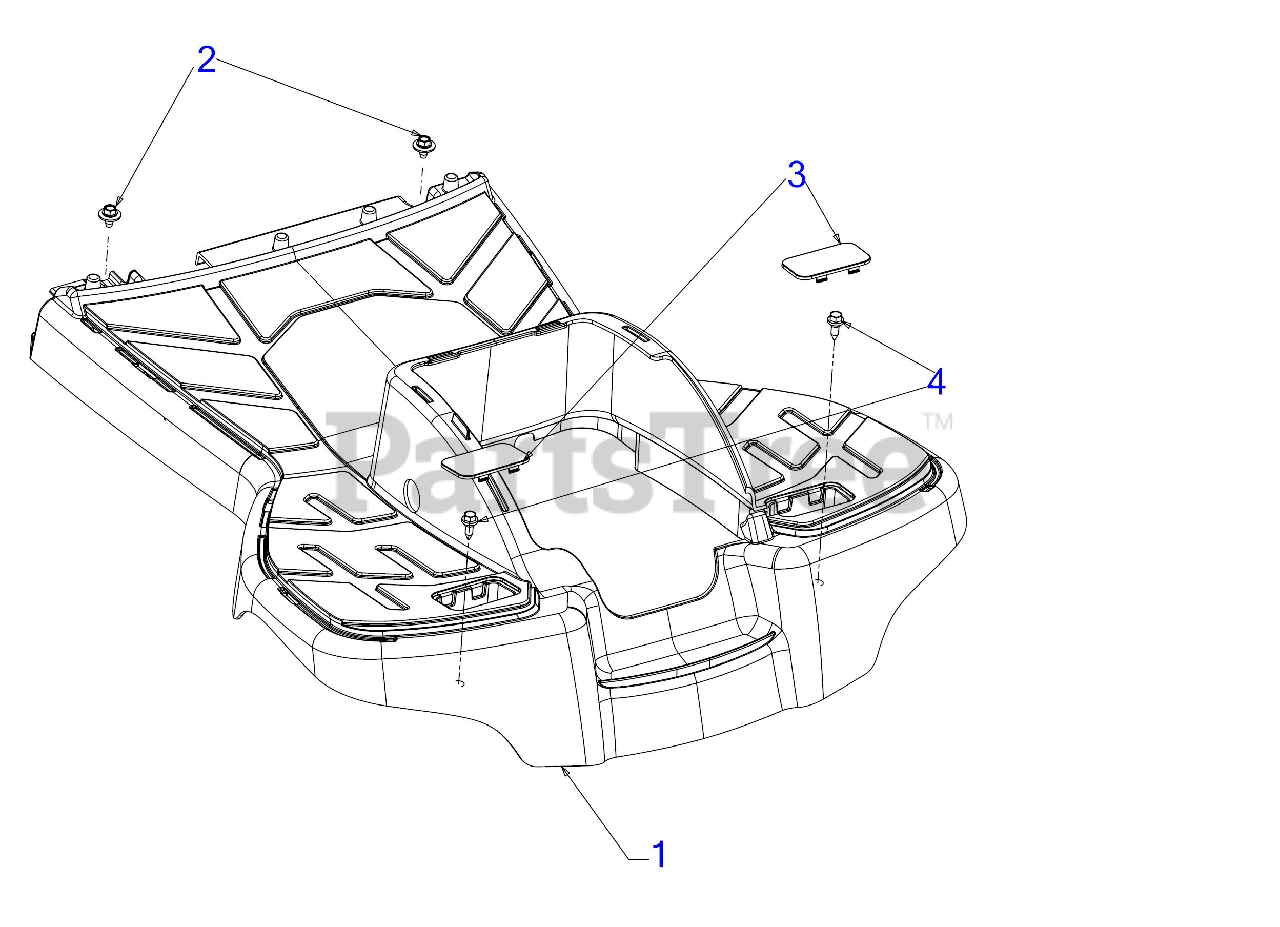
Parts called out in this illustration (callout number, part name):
1	RUNNINGBOARD W/RMC
2	SCREW 1/4-20 x .50
3	RUNNING BOARD PLUG
4	SHOULDER SCREW
